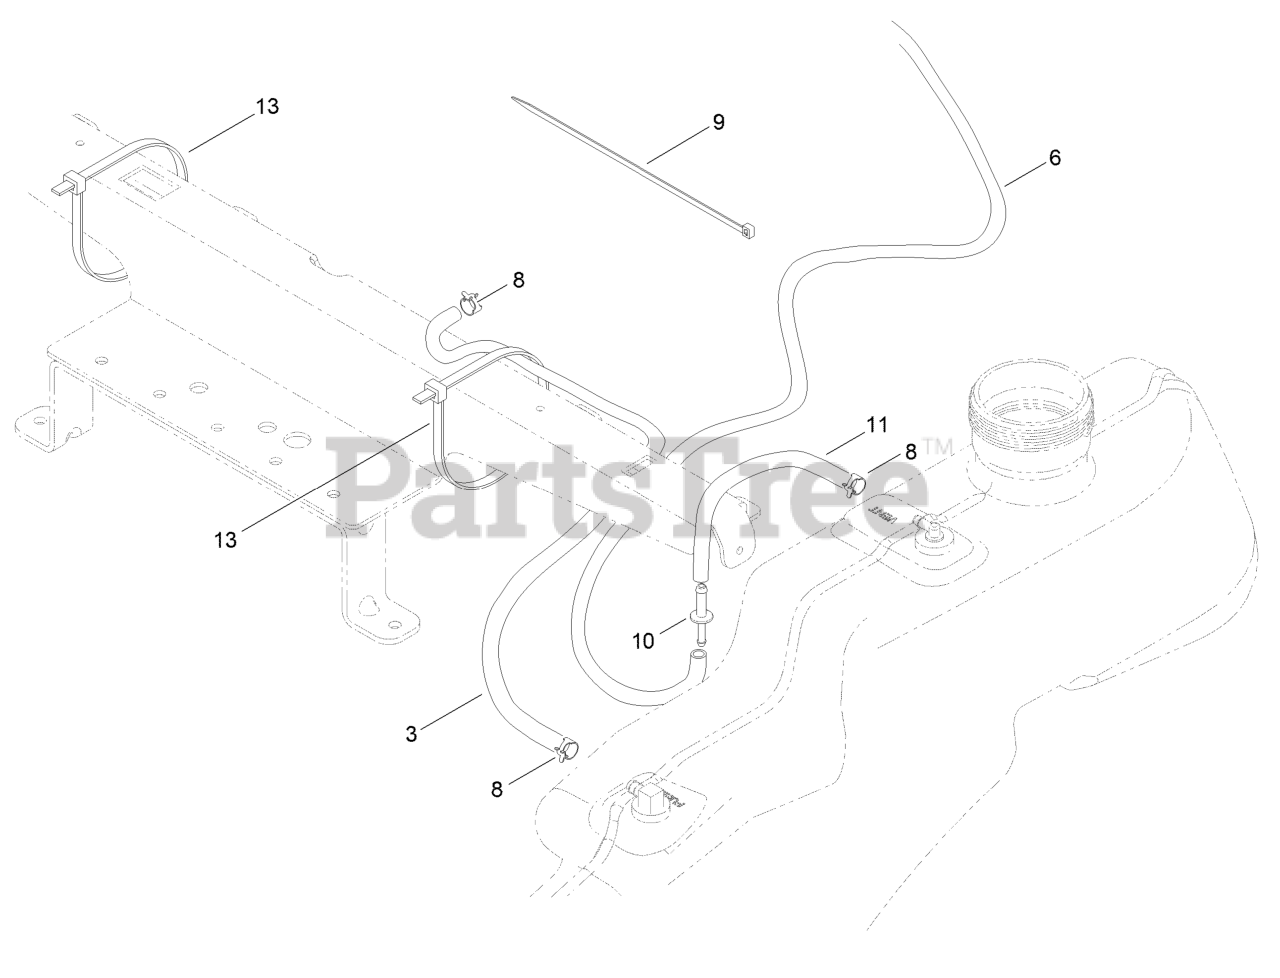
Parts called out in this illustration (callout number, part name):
3	HOSE-FUEL
6	HOSE-FUEL
8	CLAMP-HOSE
9	TIE-CABLE
10	ADAPTOR-ORIFICE
11	HOSE-FUEL
13	TIE-CABLE
